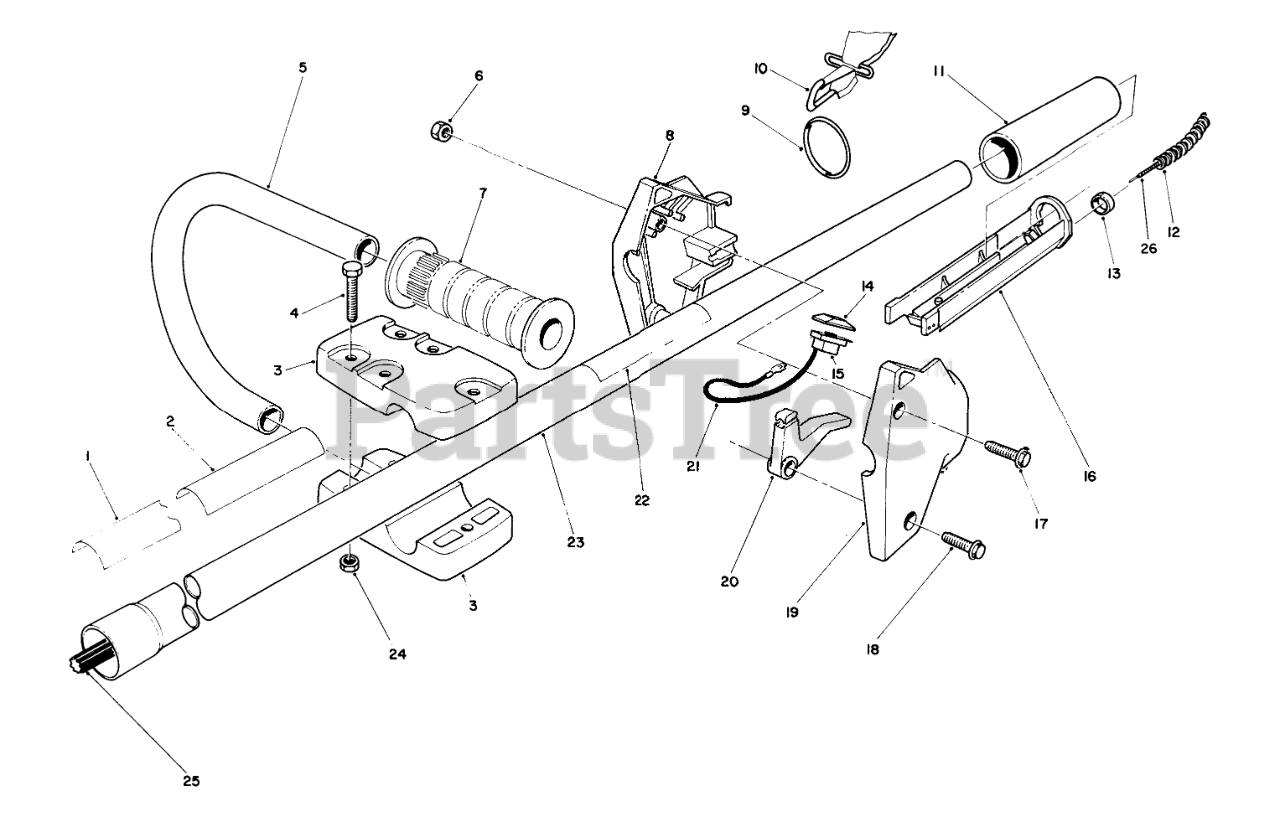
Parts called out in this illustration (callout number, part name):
1	Decal-TC 3510
2	DECAL-INSTRUCTION
3	CLAMP
4	SCREW-HH
5	J HANDLE TUBE
6	NUT-LOCK, NI
7	LH GRIP
8	THROTTLE HSG.R H
9	RING-HARNESS
10	Harness
11	GRIP - RUBBER
12	CABLE COVER
13	RING FITTING
14	SWITCH COVER-BLACK
15	SWITCH
16	TROUGH 1"
18	SCREW-HWH
19	THROTTLE HSG. L H
20	THROTTLE LEVER
21	WIRE ASM
22	Decal Danger
23	TUBE ASSEMBLY
24	NUT-LOCK, NI
25	SPLINE SHAFT
26	THROTTLE CABLE
